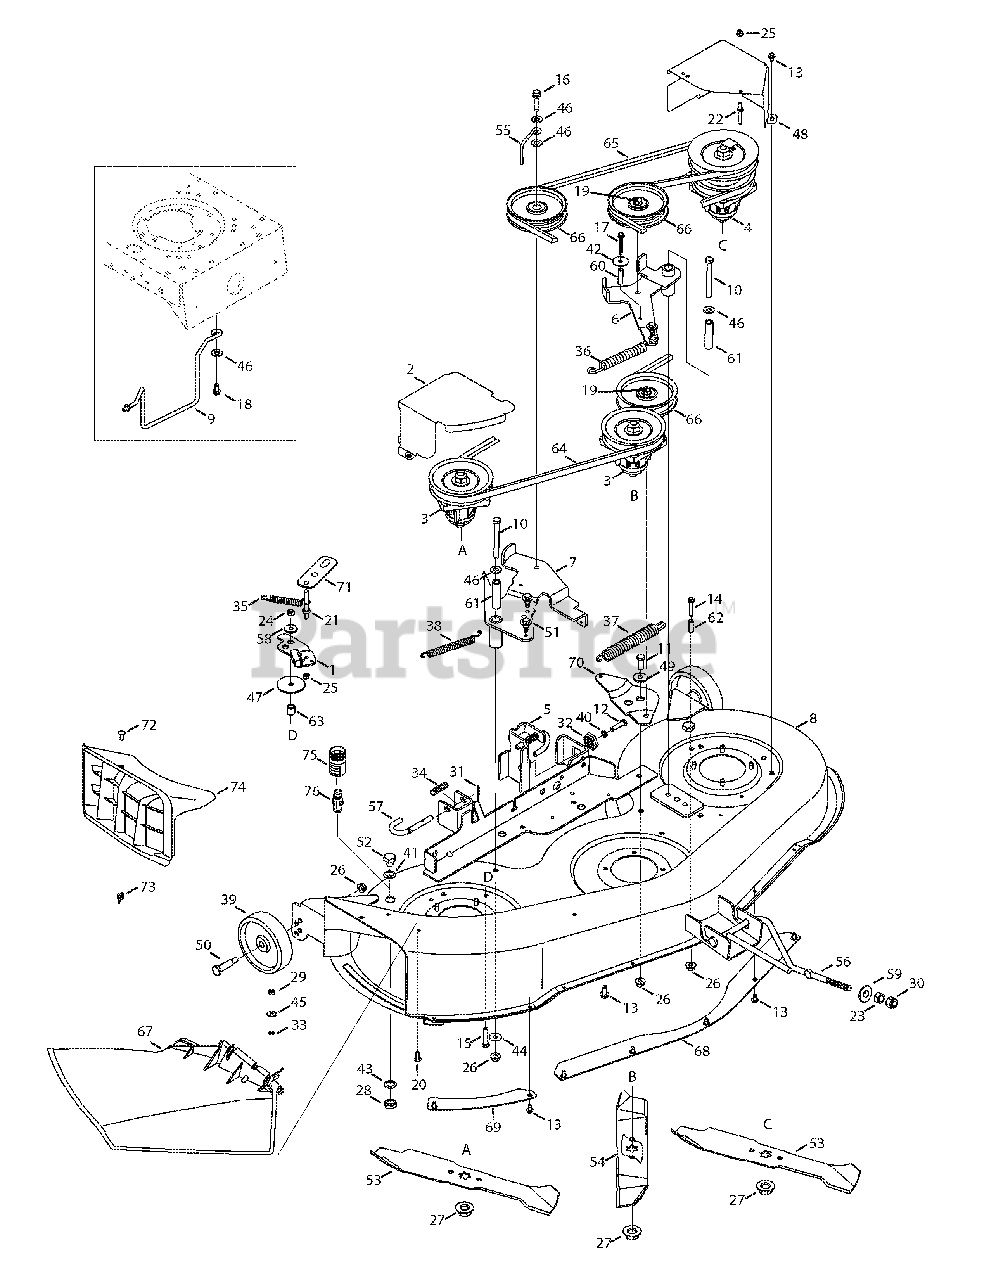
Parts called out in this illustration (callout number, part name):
1	Deck Brake Assembly
2	Deck Belt Cover RH
3	Spindle Assembly
4	Double Pulley Spindle Assy.
5	Deck Hanger Bracket Assy.
6	Idler Bracket Assembly LH
7	Idler Bracket Assembly RH
8	Deck Assembly
9	Belt Keeper Bracket
10	Hex Screw, 3/8-16 x 3.50
11	Hex Screw, 3/8-16 x 1.00
12	Hex Screw, 5/16-18 x 1.25
13	Screw, 1/4-20 x .50
14	Screw, 1/4-20 x 1.50
15	Hex Screw, 5/16-18 x 1.50
16	Sems Screw, 3/8-16 x 1.50
17	Screw, 1/4-20 x 1.75
18	Screw, 5/16-18, .750
19	Screw, 3/8-16, x 1.25
20	Screw, 1/4-20 x .75
21	Pin, 1/4-20: 3/8 x 2.685
22	Belt Guard Pin, 1/4 x 1.43 lg.
23	Hex Nut, 1/2-13
24	Flange Lock Nut, 5/16-18
25	Flange Lock Nut, 1/4-20
26	Flange Lock Nut, 3/8-16
27	Flange Nut, 5/8-18
28	Hex Nut, M16-1.5
29	Hex Nut, 1/4-20
30	Hex Lock Nut, 1/2-13
31	Cotter Pin, 1/8 x 1.25
32	Deck Adjustment Gear
33	Push Nut, .25 ID x .50 OD
34	Compression Spring .531 x 1.75
35	Extension Spring, .50 x 3.97 Lg.
36	Extension Spring, .75 x 6.835 Lg.
37	Extension Spring, .91 x 7.33 Lg.
38	Extension Spring, .56 x 5.52 lg.
39	Deck Wheel 5.0 x 1.38
40	Lock Washer, 5/16
41	Flat Washer, .64 x 1.24 x .06
42	Flat Washer, .285 x 1.25 x .06
43	Lock Washer, 5/8 Int. Tooth
44	Flat Washer, .385 x 1.0 x .135
45	Bell Washer, .265 x .75 x .062
46	Flat Washer, .406 x .875 x .059
47	Flat Washer, .406 x .875 x .059
48	Deck Belt Cover LH
49	Shoulder Spacer, .625 ID x .169
50	Shoulder Bolt .496 x 1.525: 3/8-16
51	Shoulder Screw .43 x .29:5/16-18
52	Bolt Plug, M16 x 1.5
53	Blade, 3 in 1 star, 16.28" Lg.
54	Blade, 3 in 1 star, 14.88" Lg.
55	Belt Keeper Rod
56	Front Deck Adjustment Rod
57	Deck Release Handle Rod
58	Shoulder Spacer
59	Deck Lift Pivot Cup
60	Spacer, .260 x .372 x 1.420 Lg.
61	Spacer, .380 x .625 x 2.515 Lg.
62	Spacer, .260 x .372 x 1.030 Lg.
63	Spacer, .375 x .63 x .595 Lg.
64	V-Belt, 79.10 Lg.
65	V-Belt, 90.24 Lg.
66	Idler Pulley, 4.25" dia.
67	Discharge Chute
68	Center Deck Skirt
69	RH Deck Skirt
71	Brake Bracket
72	Carriage Screw, 1/4-20 x .62
73	Wing Nut, 1/4-20
74	Mulch Plug, 46" Deck
75	Water Nozzle Adapter
76	Deck Water Nozzle
